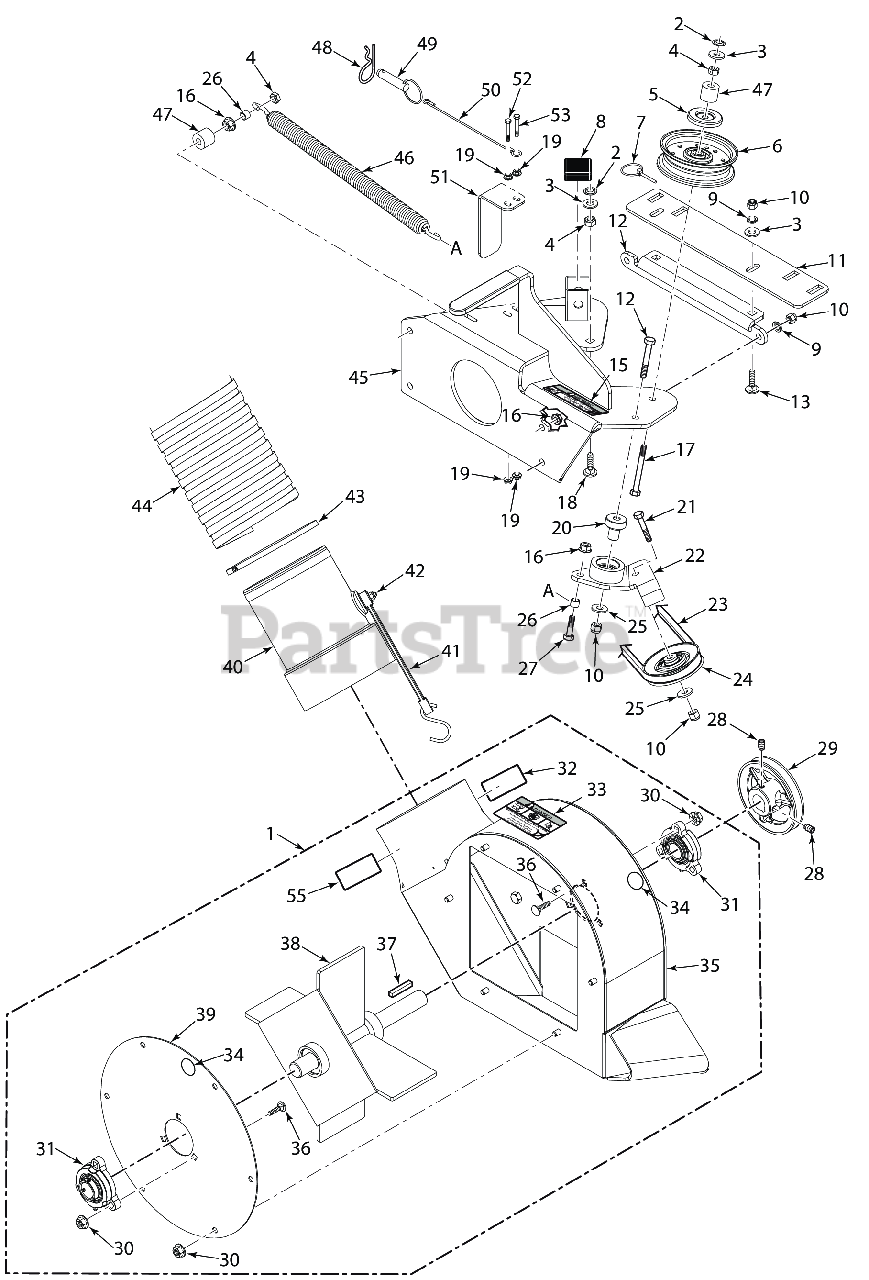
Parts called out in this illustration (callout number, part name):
1	Blowing Housing Assembly w/Fan
2	Nut, Push-On - 3/8" Dia.
3	Flatwasher, 3/8" Special (.391 x .938 x .105)
4	Bolt, Hex Head 3/8-16 x 1" Ser. Flg.
5	Quick Pin, 5/16" Dia.
6	Pulley, Idler 4" Dia. - 61" & 72"
7	Quick Pin, 5/16" Dia.
8	Cap, Square Vinyl
9	Lockwasher, 3/8" Spring, Kawasaki FX / FS
10	HEX NUT, ELASTIC STOP LOCK, 3/8-16
11	Plate, Blower Catch
12	Plate, Catch Mounting
13	SHORT SQ. NECK CARRIAGE BOLT, 3/8-16 X 1-1/4"
14	Bolt, Hex Head 3/8-16 x 2-1/4" - 61"
15	Decal, Warning - Belt Cover
16	NUT, 3/8-16 SERRATED FLANGE HEX HEAD
17	Bolt, Hex Head 3/8-16 x 3-1/2" Full Thread
18	Bolt, RDHD Carr. 3/8-16 x 1-1/2 (52" & 61")
19	NUT, 1/4-20 SERRATED FLANGE HEX HEAD
20	Pivot, Idler - 61" & 72"
21	Capscrew, Hex Head 3/8-16 x 2.0"
22	Idler Arm Assembly
22	BEARINGS, BALL, NEUTRAL RETURN
23	Belt (52)
23	Belt, GC-STT 72"
24	Pulley, 3-1/2" O.D., GC-STT 52"
25	Flatwasher, 3/8 (.391 x .938 x .105 HD) Grade 8
26	Spacer, Deck Assist
27	Bolt, Hex Head 3/8-16 x 1-1/4" Grade 8
28	Setscrew, Hex Socket Knurl Cup Pt. 5/16 - 18 (nylock)
29	Pulley, 4-3/4" O.D. - 1" Bore
30	Nut, Serrated Flange 5/16-18 (Right Front Engine Mounting, Briggs and Kohler Only)
31	Bearing Assembly
32	Decal, Blower
33	Decal, Danger
34	Decal, Grease Point
35	Blower Housing Weldment w/Decals
36	Bolt, Carriage 5/16-18x1" (large frame units only)
37	KEY 1/4 X 1/4 X 1 1/2"(FOR 1" CRANKSHAFT
38	Fan Weldment, Narrow
39	COVER, BLOWER HOUSING
40	Adapter, Blower GC-STC,
41	Rubber Strap 7-3/4"
42	SERR. FLG. HEX HEAD CAPSCREW, 5/16-18 X 3/4
43	Clamp, 6-1/2"
44	Hose, 6" x 56"
45	Blower Mounting Frame w/ Decal
46	Spring, Helper (61" Cutter Deck Only)
47	SPACER, J-PULL ROD
48	Hair Pin Cotter, .243 x 4"
49	Pin, Ring 1/2" x 2-1/4"
50	Lanyard, Deck Height Pin
51	Belt Cover
52	Bolt, Hex Head, 1/4-20 x 1-1/2"
53	SERR. FLG. HEX HEAD CAPSCREW, 5/16-18 X 3/4
54	Grip, Deck Latch Lever
55	Decal, Rotating Blower
